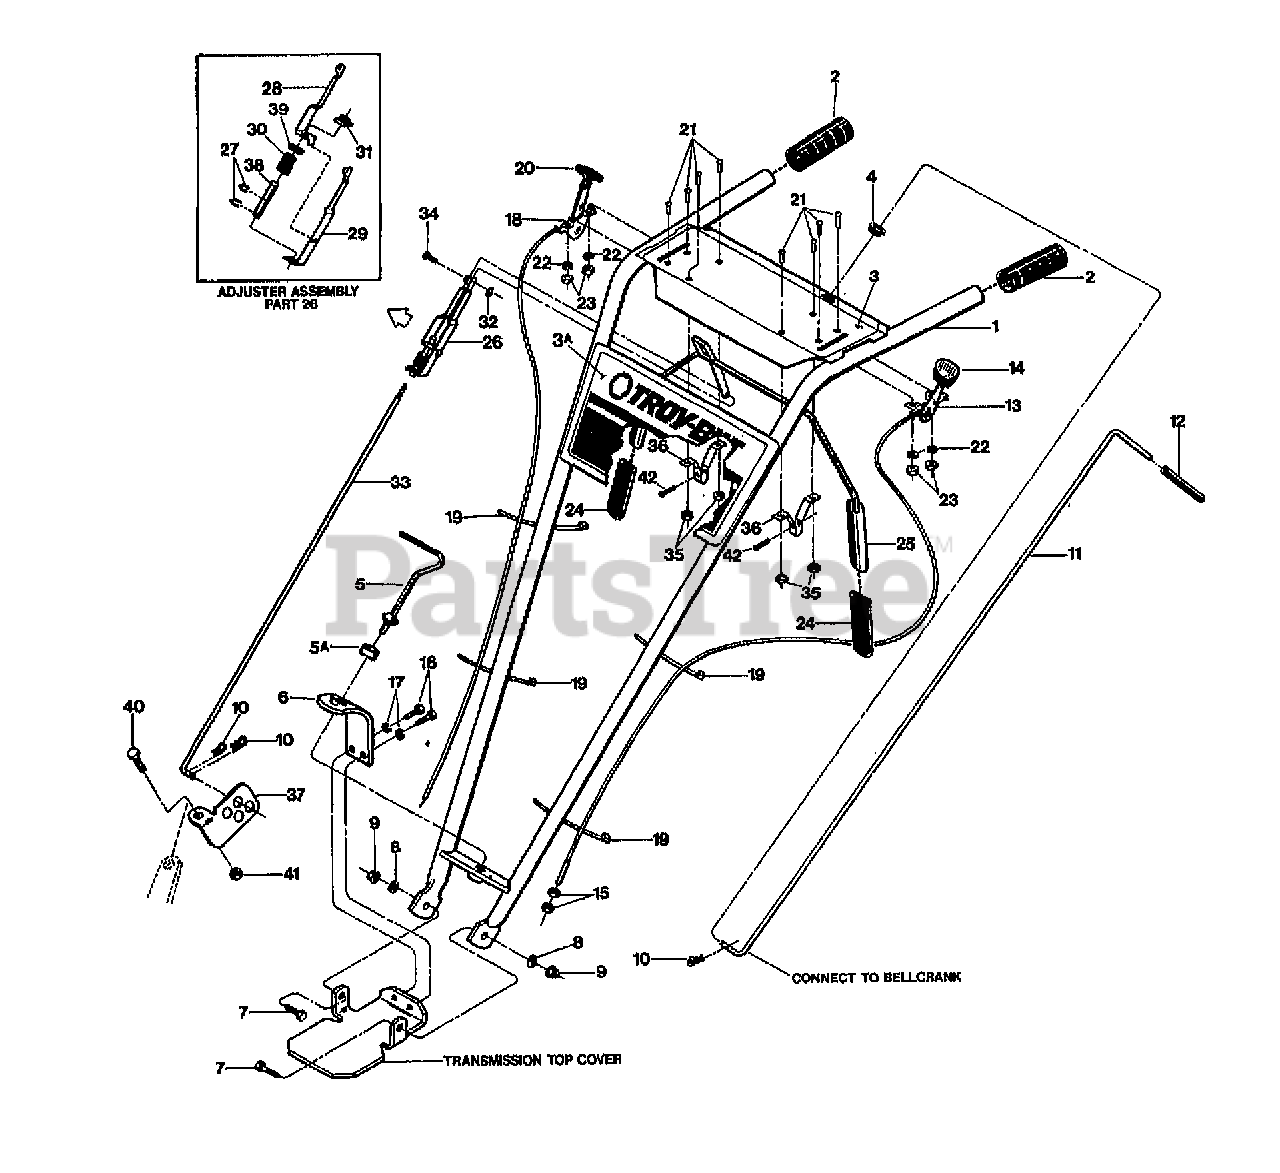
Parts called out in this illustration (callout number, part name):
1	ASSM-HANDLEBAR W/GRIPS (INCL. 2,3,3A,4)
2	GRIP-H/BAR SMOOTH
3	DECAL-CONTROL PANEL
3A	DECAL-GRAPHICS PANEL ECONO
4	BUSHING-NYLON
5	ASSM-STUD H/B
5A	WASHER-1.0X.38X.375
6	PLATE-HANDLEBAR ADJUST
7	SCR-HH 3/8-16X1.0 G5 ZP
8	WASHER-FLAT 3/8 SAE
9	NUT-LOCK 3/8-16 NYLON ZP
10	PIN-CLIP .08
11	ROD-REV W/GRIP OPC (INCL. #12)
12	GRIP-CONTROL ROD
13	CABLE-WHEEL CLUTCH OPC (INCL. 14,15,19,21-23)
14	KNOB-WHEEL DRIVE CABLE
15	NUT-HEX 5/16-24
16	SCR-HH 3/8-16X.75 G5 ZP
17	WASHER-LK .375 @ DEPL
18	CABLE-THROTTLE ECONO OPC (INCL. 20)
19	TIE-RED
20	KNOB-THROTTLE CABLE
21	SCR-RH M10-32X.5 MACH
22	WASHER-LK M10
23	NUT-HH M10-32X.125
24	GRIP-PADDLE SM FRAME OPC
25	BAIL W/GRIPS OPC (INCL. TWO #24)
26	ASSM-ADJUSTMENT OPC (INCL. 27-30,38-39)
27	RING-KLIP .500 ZINC
28	ADJUSTER-RT SIDE OPC
29	ADJUSTER-LT SIDE OPC
30	SPRING-ADJUSTER OPC
31	WELDNUT 5/16-18
32	RING-KLIP .188 DIA
33	ROD-CONTROL OPC
34	ASSM-PIN & CLIP (SMALL FRAME)
35	NUT W/LKWASHER #10-32 ZP
36	BRACKET-BAIL OPC
37	SWIVEL-SMALL FRAME
38	BUSHING-.5X.334X2.88
39	WASHER-.75X.51X.06 ZP
40	SCR-HH 1/4-20X.75 G5 ZP
41	NUT-LK 1/4-20
42	SCR-HWH 1/4-20 X .5 STH
